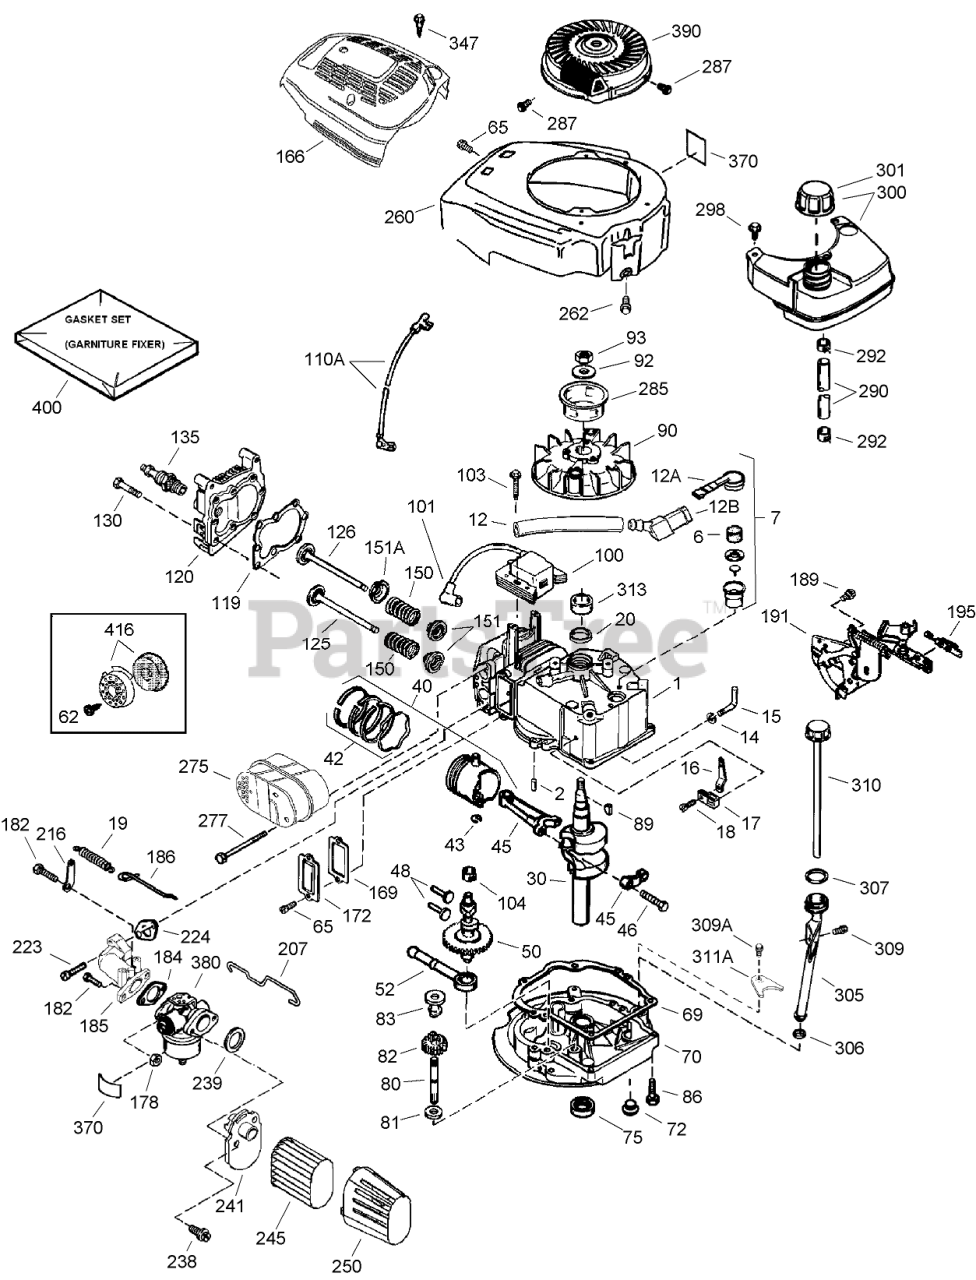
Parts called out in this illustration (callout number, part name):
1	Cylinder ASM
2	Pin-Dowel
6	Element-Breather
7	Breather ASM
12	Tube-Breather
12A	Breather Cover and Tube ASM
12B	Elbow-Tube, Breather
14	Washer-Flat
15	Governor Rod ASM
16	Lever-Governor
17	Clamp-Lever, Governor
18	Screw (T-15, 8-32 x 19/64)
19	Spring-Extension
20	Seal-Oil
30	Crankshaft
40	Piston, Pin and Ring Set (STD)
40	Piston, Pin and Ring Set (.010 O S)
42	Ring Set (STD)
42	Ring Set (.010 O S)
43	Ring-Retaining, Piston Pin
45	Connecting Rod ASM
46	Bolt-Rod, Connecting
48	Lifter-Valve
50	Camshaft ASM (Exhaust M C R)
52	Oil Pump ASM
62	Screw (8-32 x 3/8)
65	Screw (10-24 x 9/16)
69	Gasket-Flange, Mounting
70	Mounting Flange ASM
72	Plug-Drain, Oil
75	Seal-Oil
80	Shaft-Governor
81	Washer-Flat
82	Governor Gear ASM
83	Spool-Governor
86	Screw (1/4-20 x 1-1/4)
89	Key-Flywheel
90	Flywheel
92	Washer-Belleville
93	Nut-Flywheel
100	Ignition-State, Solid
101	Cover-Spark Plug
103	Screw (T-15, 10-24 x 15/16)
104	Bushing-Cam
110A	Wire-Ground
119	Gasket-Head, Cylinder
120	Head-Cylinder
125	Valve-Exhaust (1/32 OS)
125	Valve-Exhaust (STD)
126	Valve-Intake (STD)
130	Screw (5/16-18x1-1/2)
135	Spark Plug-Resistor (R J19 L M)
150	Spring-Valve
151	Cap-Valve, Spring
151A	Seal-Valve, Intake
166	Shroud-Engine
169	Gasket-Cover, Valve
172	Cover-Valve
178	Nut and Lock Washer (1/4-28)
182	Screw (1/4-28 x 7/8)
184	Gasket
185	Pipe-Intake
186	Link-Governor
189	Screw (1/4-20 x 3/8)
191	Bracket-Brake
195	Terminal
207	Link-Throttle
216	Lever-Adjusting, R P M
223	Screw (1/4-20 x 1)
224	Gasket-Pipe, Intake
238	Screw (10-32 x 49/64)
239	Gasket-Cleaner, Air
241	Collar-Cleaner, Air
245	Filter-Cleaner, Air (Paper)
250	Cover-Cleaner, Air
260	Housing-Blower
262	Screw (1/4-20 x 1/2)
275	Muffler
277	Screw (1/4-20 x 2-9/32)
285	Cup-Starter
287	Screw (8-32 x 21/64)
290	Line-Fuel, Low Permeation (8.62)
292	Clamp-Line, Fuel
298	Screw (10-32 x 35/64)
300	Fuel Tank ASM
301	Cap-Fuel (Black) (1-1/2 I D)
305	Tube-Fill, Oil
306	O-Ring
307	O-Ring
309	Screw (10-32 x 1/2)
309A	Screw (10-24 x 3/4)
310	Dipstick
311A	Bracket-Holddown
313	Spacer
347	Screw (10-32 x 27/32)
